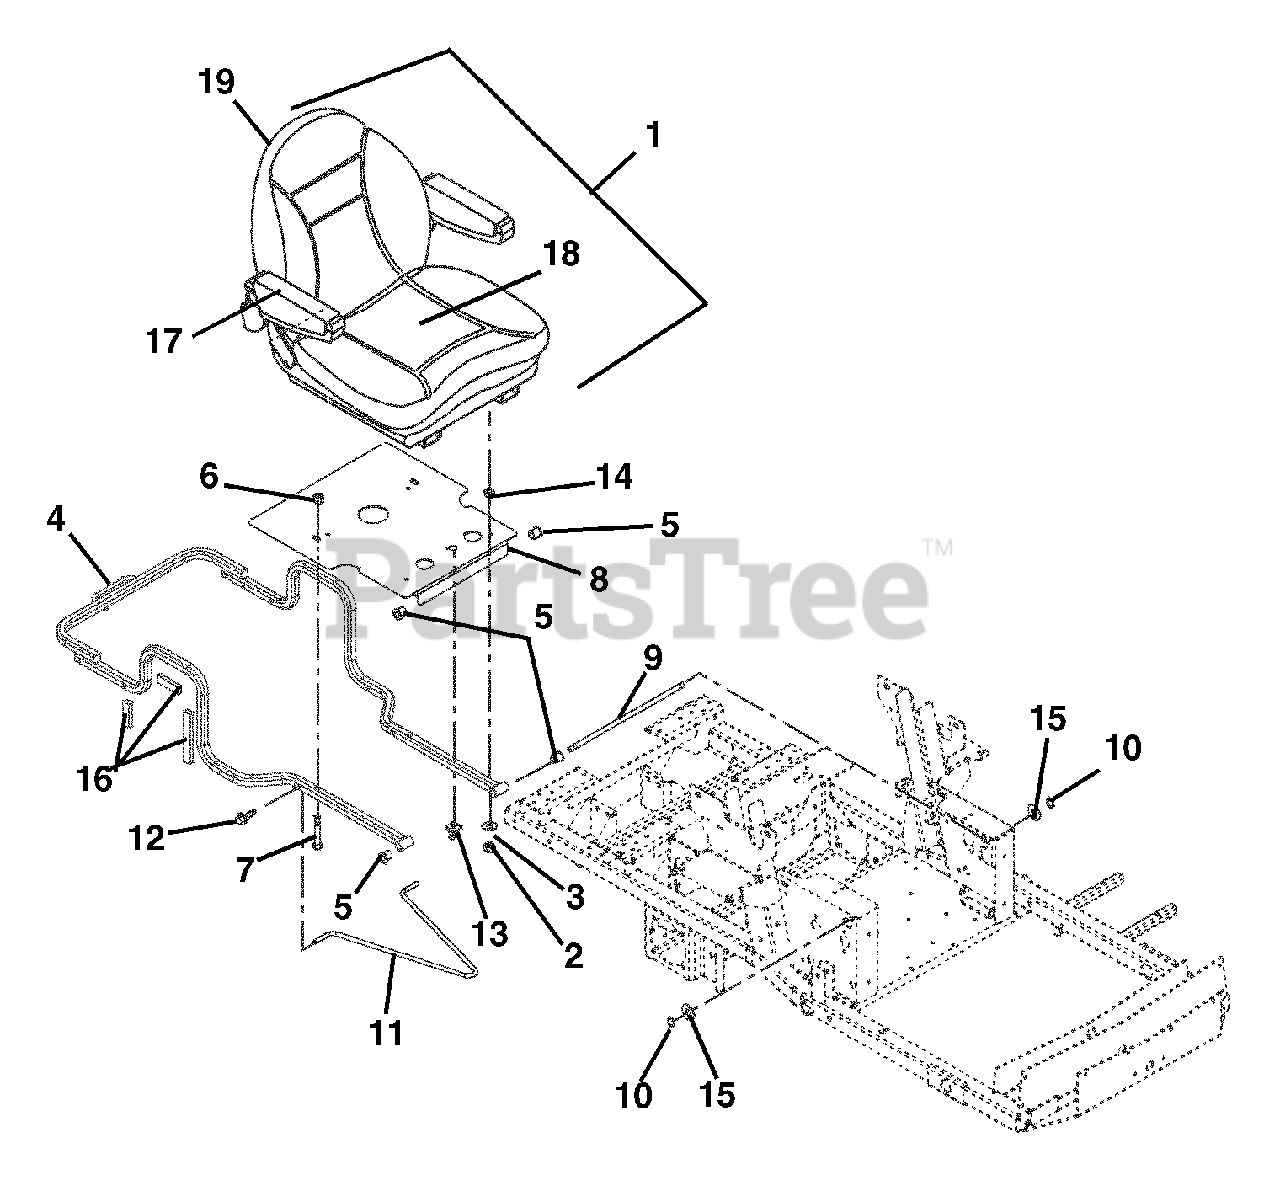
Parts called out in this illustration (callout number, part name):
1	Seat-Suspension
2	Nut-Locking-Nylon M8-1.25
3	Washer-Flat-Steel .38 x .875 x .083
4	Weldment, Hood Frame
5	Bushing-Flange .515 x .750 x .745 x 1.00
6	Nut-Locking-Top-Flange .38-16
7	Bolt-Rib Neck .38-16 x 1.50
8	Weldment, Seat Pivot Mount
9	Rod-Seat Frame Pivot
10	Ring-Retaining-External .500 x .050
11	Rod-Prop
12	Screw-Tapping .25-20 x .50 Hex Washer Head
14	Bushing-Sleeve .377 x .624 x .235
15	Washer-Flat-Steel .531 x 1.06 x .095
16	Tape, VHB
17	Kit-Arm Pad (1 per bag)
18	Kit, Seat Cushion
19	Kit, Back Cushion
